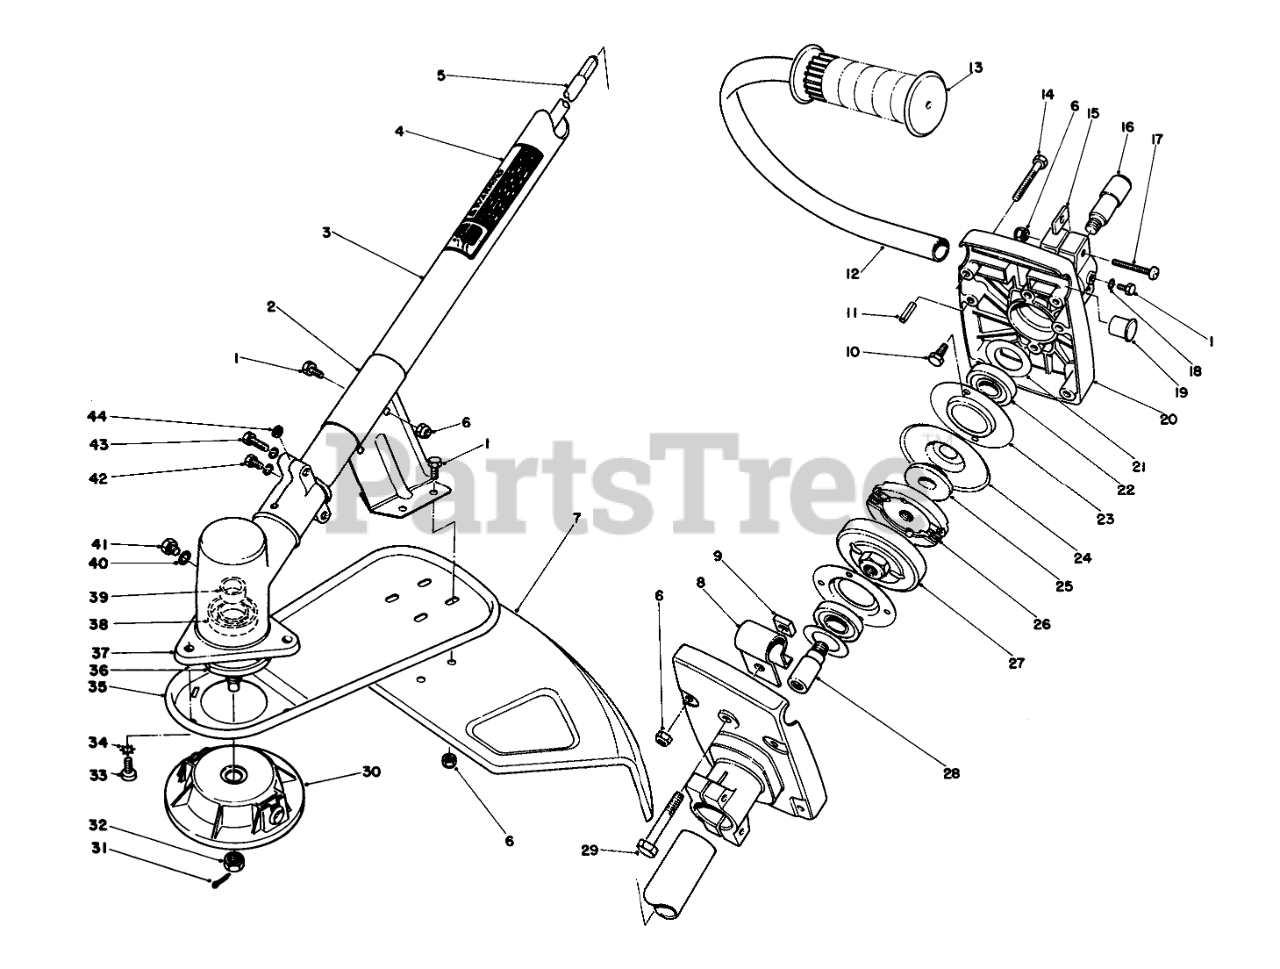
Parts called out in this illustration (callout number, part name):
1	SCREW-SHH
2	SHIELD BRKT
3	Lower Tube Assembly (Incl. Ref. #4)
4	Decal
5	Drive Shaft
6	NUT-LOCK, NI
7	GRASS SHIELD R
8	Clamp-Handle
9	Nut-Square
10	SCREW-TAPTITE
11	PIN-SPRING
12	J-Handle
13	LH GRIP
14	Screw-Machine Hex. Hd.
15	Washer-Housing
16	Shaft-Clutch, Input
17	Screw-Machine Cross Recess Pan Hd.
18	WASHER-LOCK/SP
19	Plug Cap
20	Housing-Clutch
21	FLAT WASHER
22	BEARING-BALL
23	Retainer-Bearing
24	CLUTCH SHIELD-WILLMAR
25	Spacer-Clutch
26	Clutch Assembly
27	Drum Assembly
28	Shaft-Clutch, Output
29	45050-T/ST FRENCH 2
30	CUTTER HEAD-PLASTIC
31	PIN-COTTER
33	SCREW
34	WASHER-LOCK, EXT
35	SHIELD SUPPORT R
36	DUST CAP F/W
37	Gear Case Assembly (Incl. Ref. #32, 36, 3844)
38	OIL SEAL
39	SPLINED SLEEVE
40	GASKET
41	HHMS SCREW
42	HHMS SCREW
43	HHMS SCREW
44	WASHER
